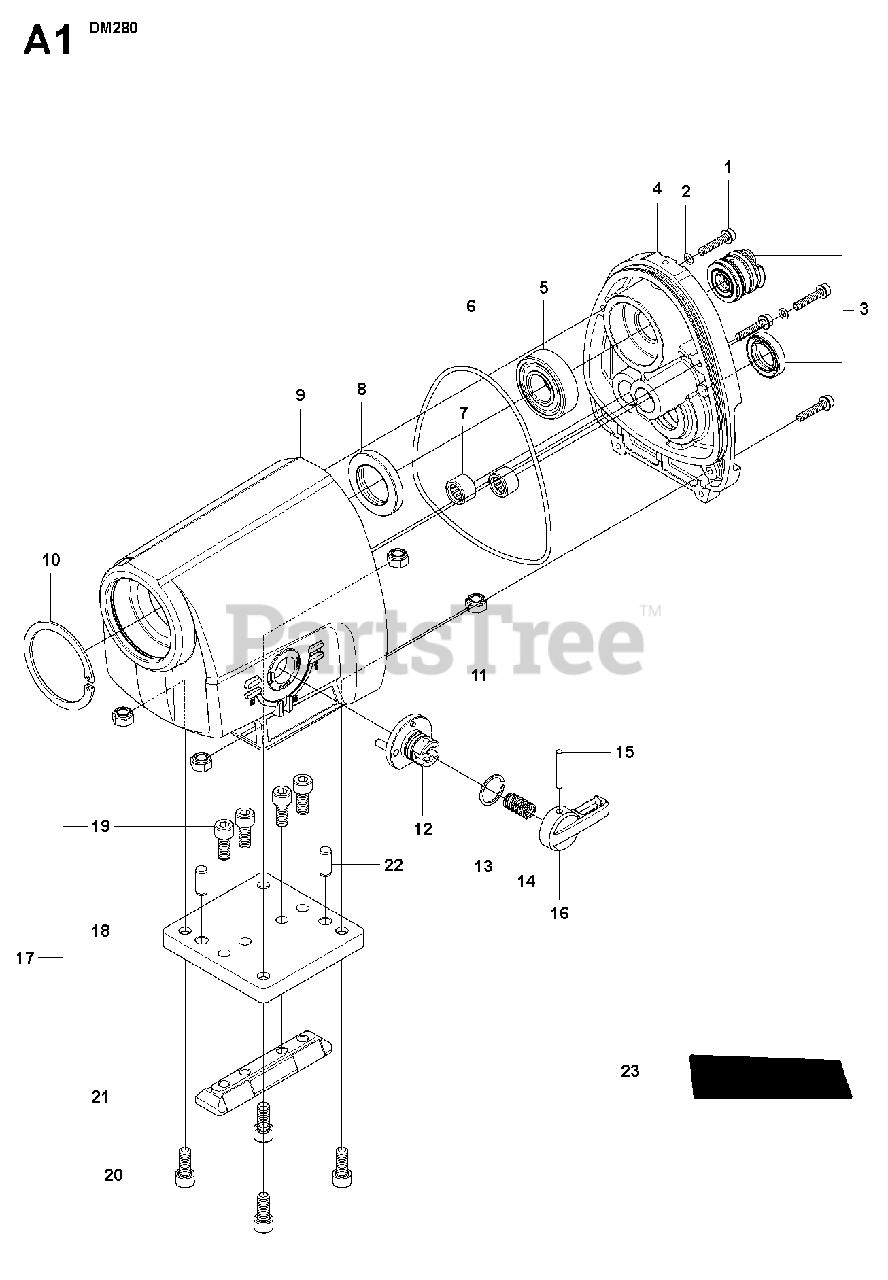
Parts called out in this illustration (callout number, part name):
1	SCREW IHSCFM
5	BALL BEARING
7	NEEDLE BEARING
11	HEXAGON LOCKING NUT
15	PARALLEL PIN
22	PARALLEL PIN
23	LABELLow speed version
23	LABELHigh speed version
